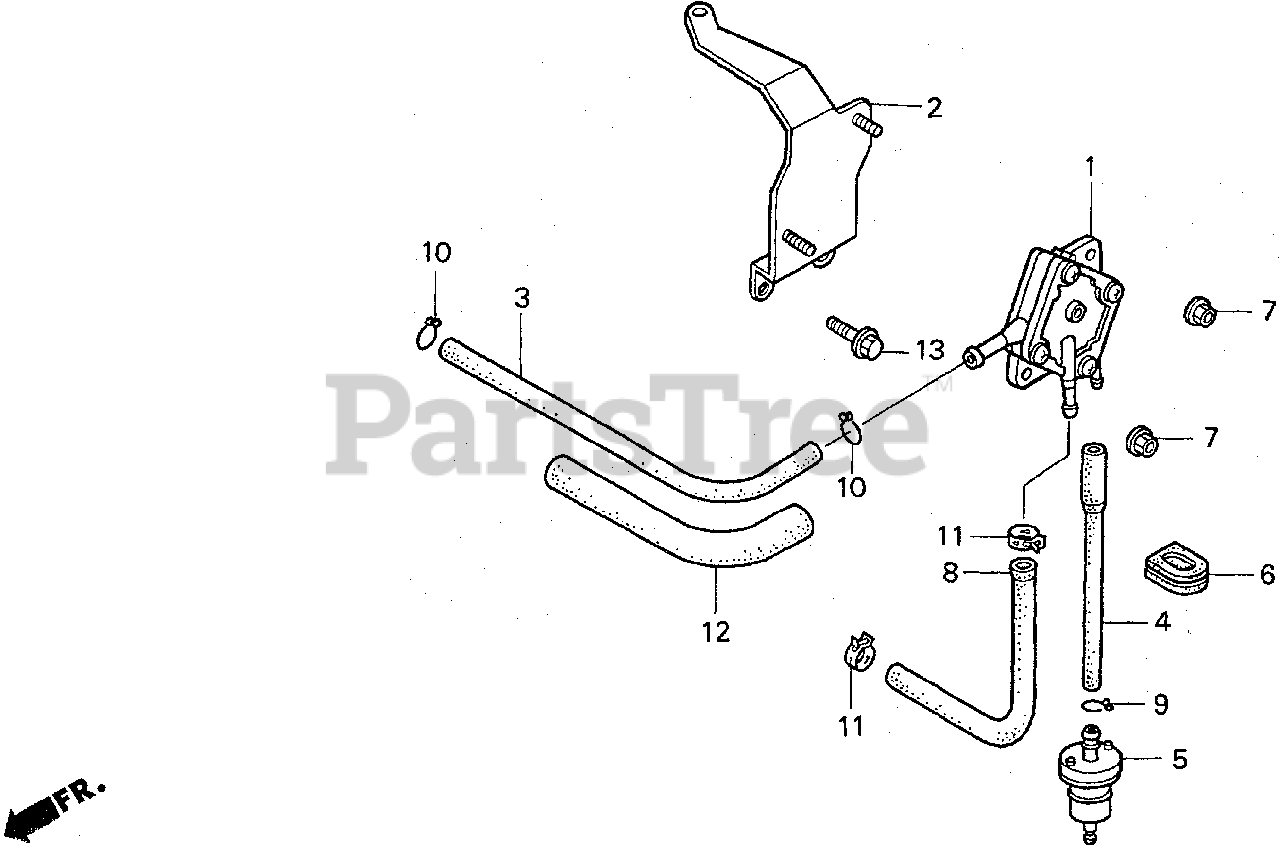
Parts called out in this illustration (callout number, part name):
1	PUMP ASSY., FUEL
2	STAY, FUEL PUMP *R8* (BRIGHT RED)
2	STAY, FUEL PUMP *NH1* (BLACK)
3	TUBE, FUEL
4	TUBE B, FUEL
5	FILTER, FUEL
6	GROMMET, WIRE
7	NUT, FLANGE (6MM)
8	BULK HOSE, FUEL (5.5X3000) (5.5X205)
9	CLIP, TUBE (B8)
10	CLIP, TUBE (B10)
11	CLIP, TUBE (D10.5)
12	BULK HOSE, VINYL (11X13X3000) (11X13X160)
13	BOLT, FLANGE (6X8)
